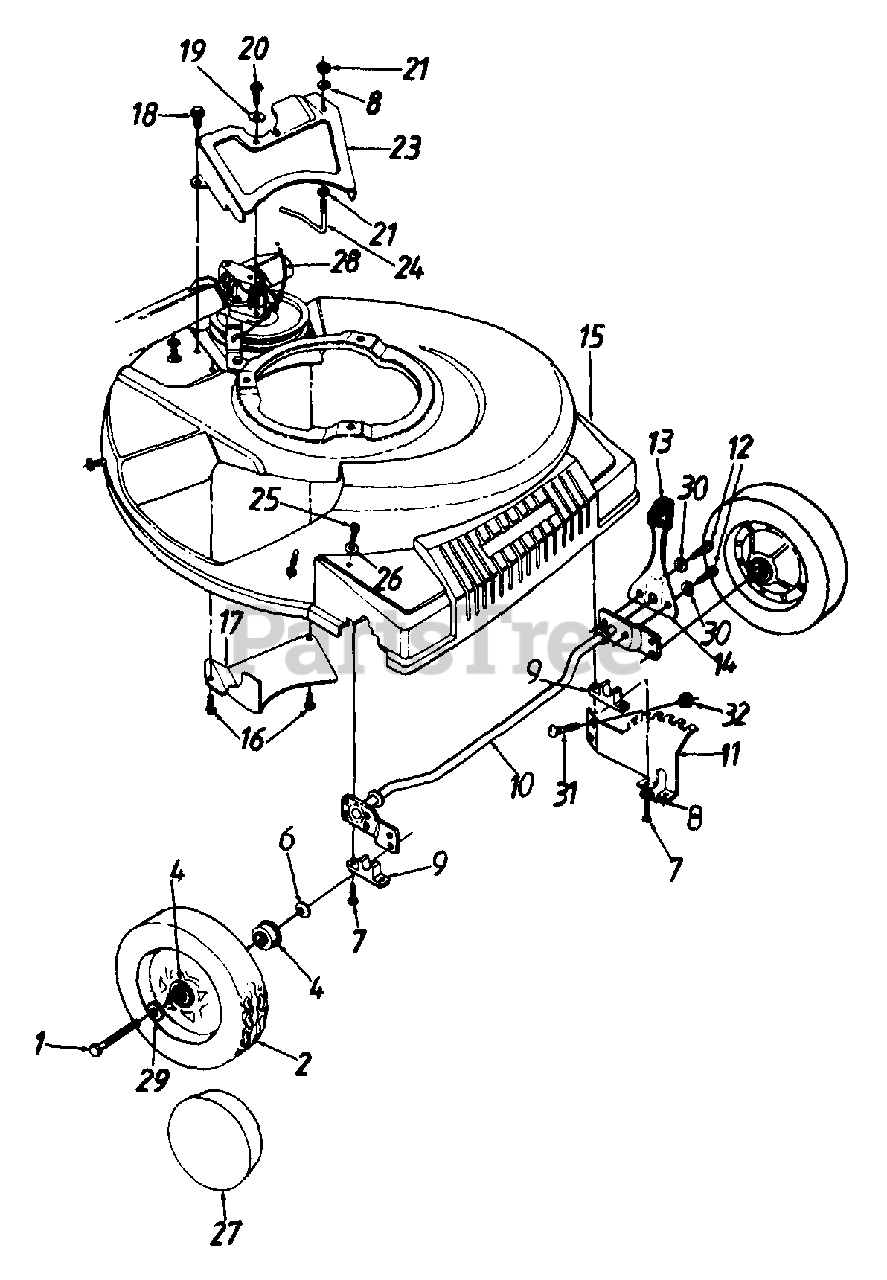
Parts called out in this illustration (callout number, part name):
1	Front Axle Bolt
2	Wheel Ass'y. Comp.
4	Flange Ball Brg. .501" I.D.
6	Bell-Wash. .380" I.D. x .88
7	Hex Wash. Hd. Scr. 1/4-20 x 1" Lg.
8	L-Wash. 1/4" I.D.
9	Block Bushing
12	Hex Wash. Hd. TT-Tap Scr. 1/4-20 x .38" Lg.
13	Knob
14	Spring Lever
15	Plastic Front End
16	Hex B-Tap Scr. 1/4" x .38"
19	Bell-Wash. .265" I.D. x .75"
20	Hex Wash. Hd. B-Tap Scr. 1/4 x .62" (Spec.)
21	Hex Nut 1/4-20 Thd.
25	Torx Truss Hd. Scr. 5/16 x .75"
26	Bell-Wash. .345" I.D. x .88" O.D.
27	Hub Cap
28	S.P. Cable 50" Lg.
29	Wave Wash. .51" I.D. x .75" O.D.
30	External L-Wash. 1/4" I.D.
31	Carr. Bolt 1/4-20 x .5" Lg.
32	Hex L-Nut 1/4-20 Thd.
